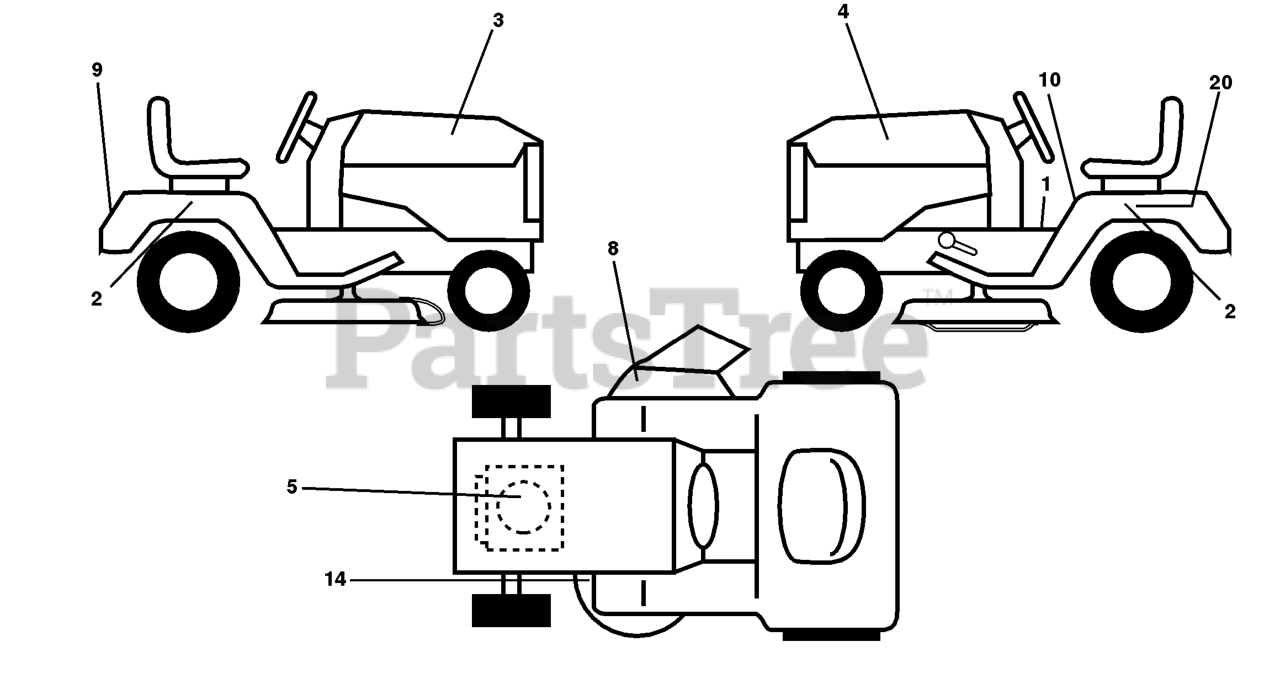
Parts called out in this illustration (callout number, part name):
3	DECAL, HOOD LH LTH120
4	DECAL, HOOD RH LTH120
5	DECAL HP ENGINE
8	DECAL WARNING (ENGLISH/FRENCH)
9	DECAL FENDER HUSQ
10	DECAL FENDER DANGER
14	DECAL V-BELT SCHEMATIC
20	DECAL BTRY SYMBOLS
